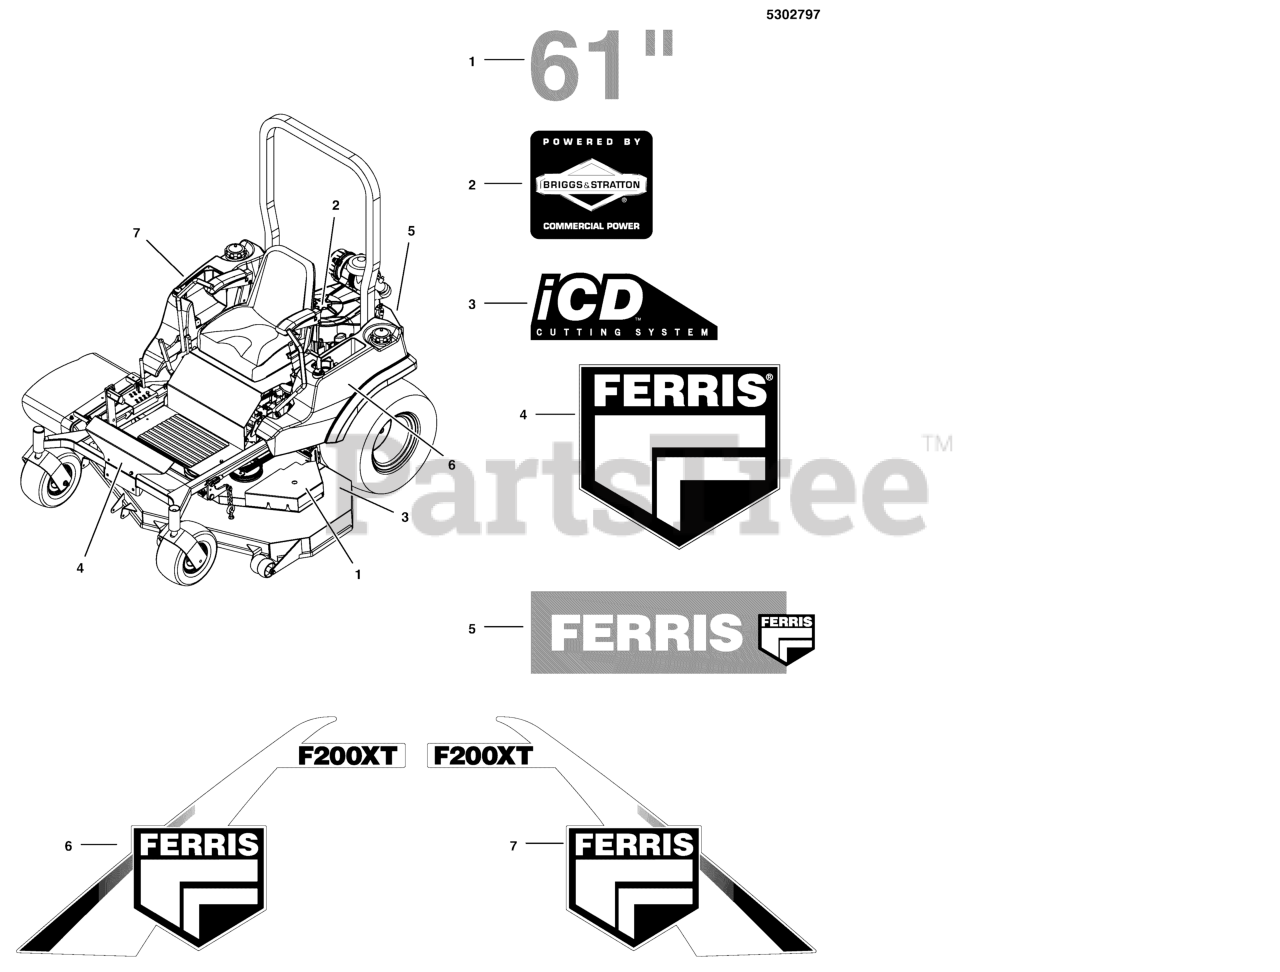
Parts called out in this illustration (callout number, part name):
1	DECAL, 61
3	DECAL, ICD CUTTING SYSTEM
4	DECAL, FERRIS LOGO, MEDIUM
5	DECAL, FERRIS TEXT & LOGO
6	DECAL, BADGE, LH, F200XT
7	DECAL, BADGE, RH, F200XT
